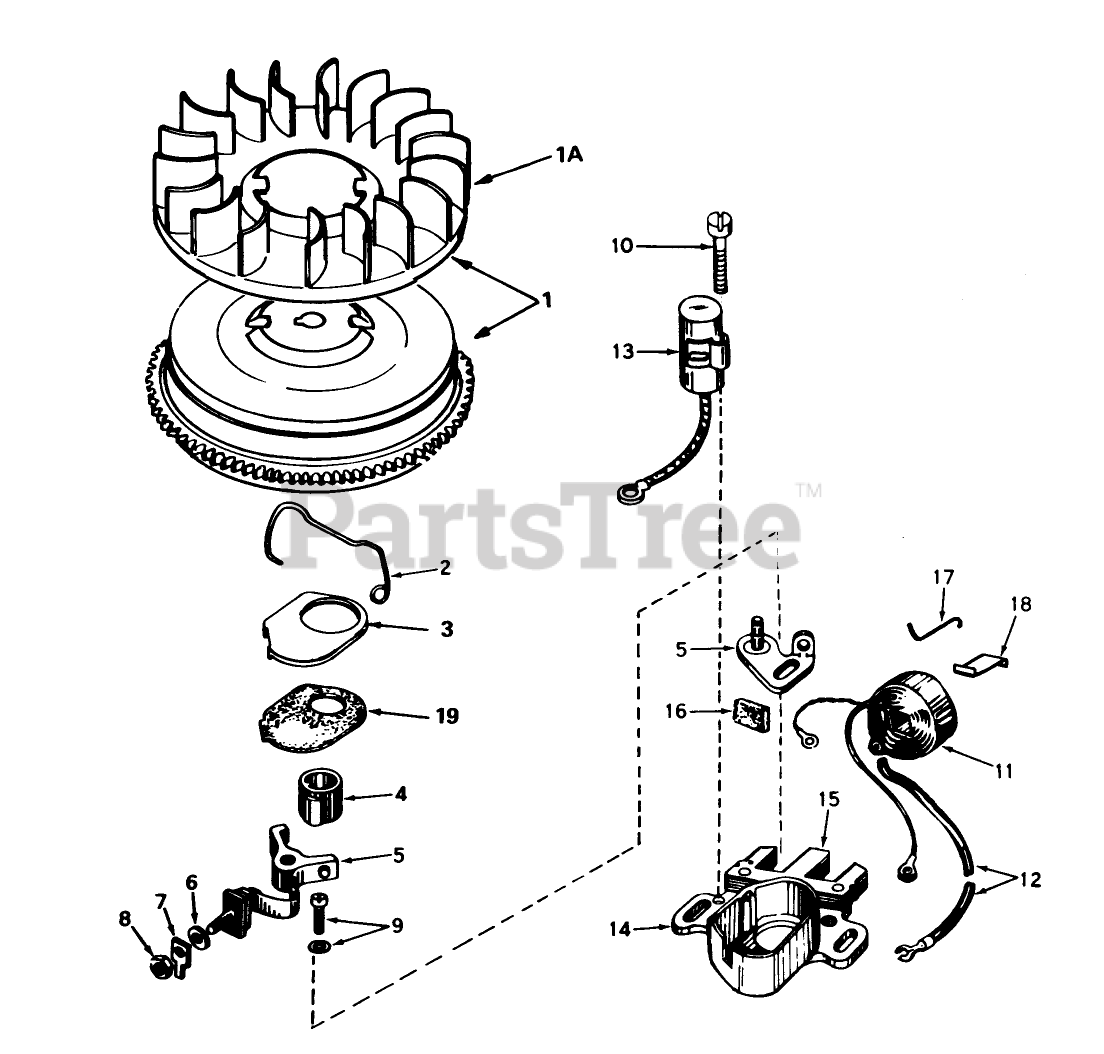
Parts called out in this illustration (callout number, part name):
1	Flywheel (Incl. Ref. #1A, 3 & 3A)
2	Spring Breaker Box
3	Cover-Dust
3A	Gasket, Dust Cover
4	Cam-Breaker
5	Breaker Assy.
7	Terminal, Ground
9	Breaker Screw
10	Condenser Screw
11	Coil Assy., (Incl. Ref. #12)
12	Wire, Lead
13	Condenser
14	Core & Plate
15	Stator Assy. (Incl. Ref. #2, 3, 3A, 5 thru 14 & 16 thru 18)
16	Felt,Cam Wiper
17	Clip, Coil
18	Spring Coil Wedge
